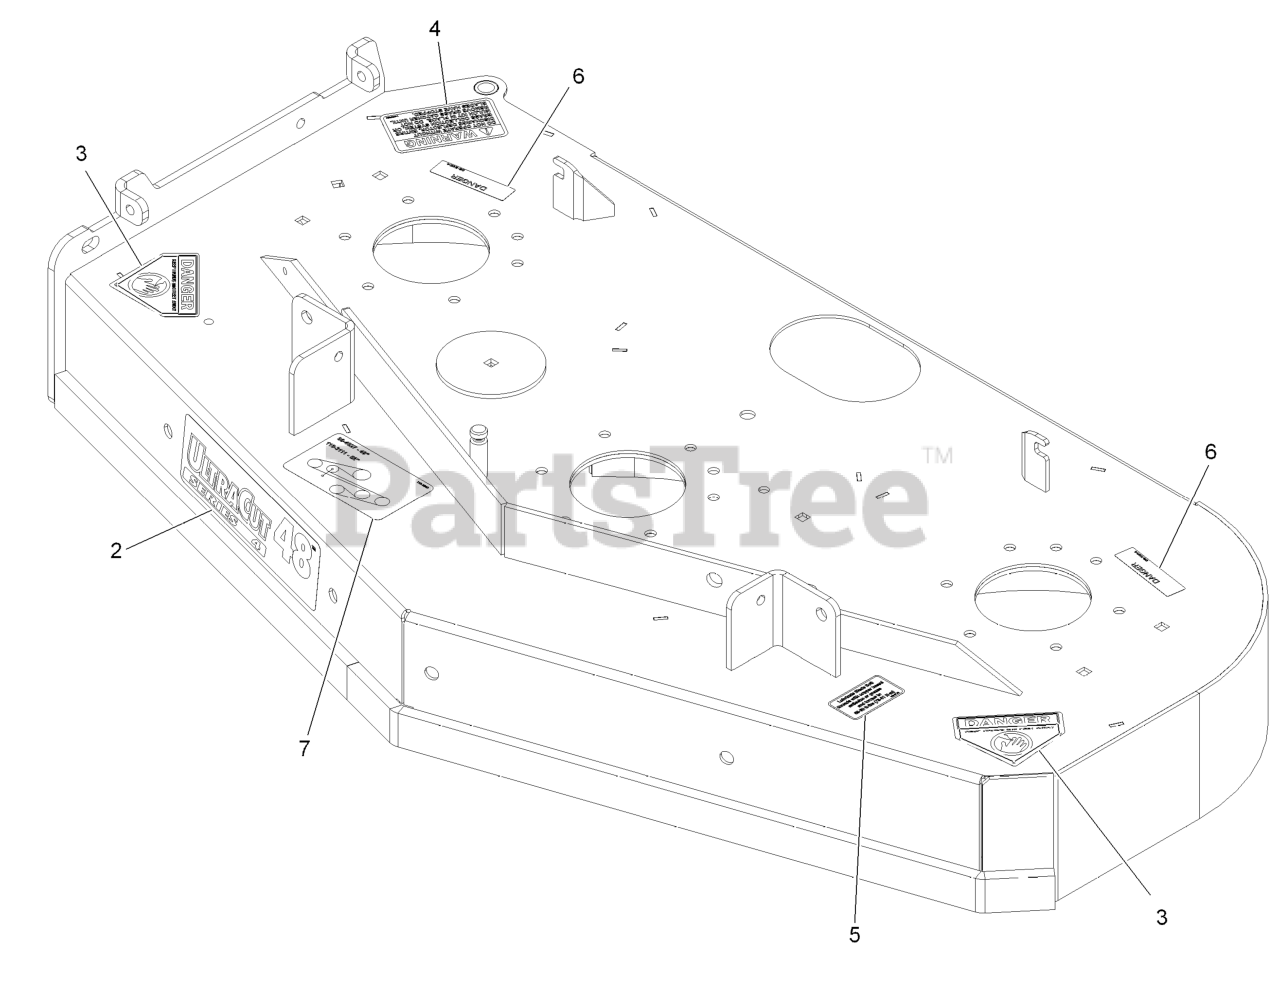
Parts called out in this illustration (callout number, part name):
2	DECAL,ULTRACUT 48 SERIES
3	DECAL-DANGER
4	DECAL-WARNING, DISCHARGE
5	DECAL,BOLT TORQUE
6	DECAL-COVER, MISSING
7	DECAL-BELT ROUTING
